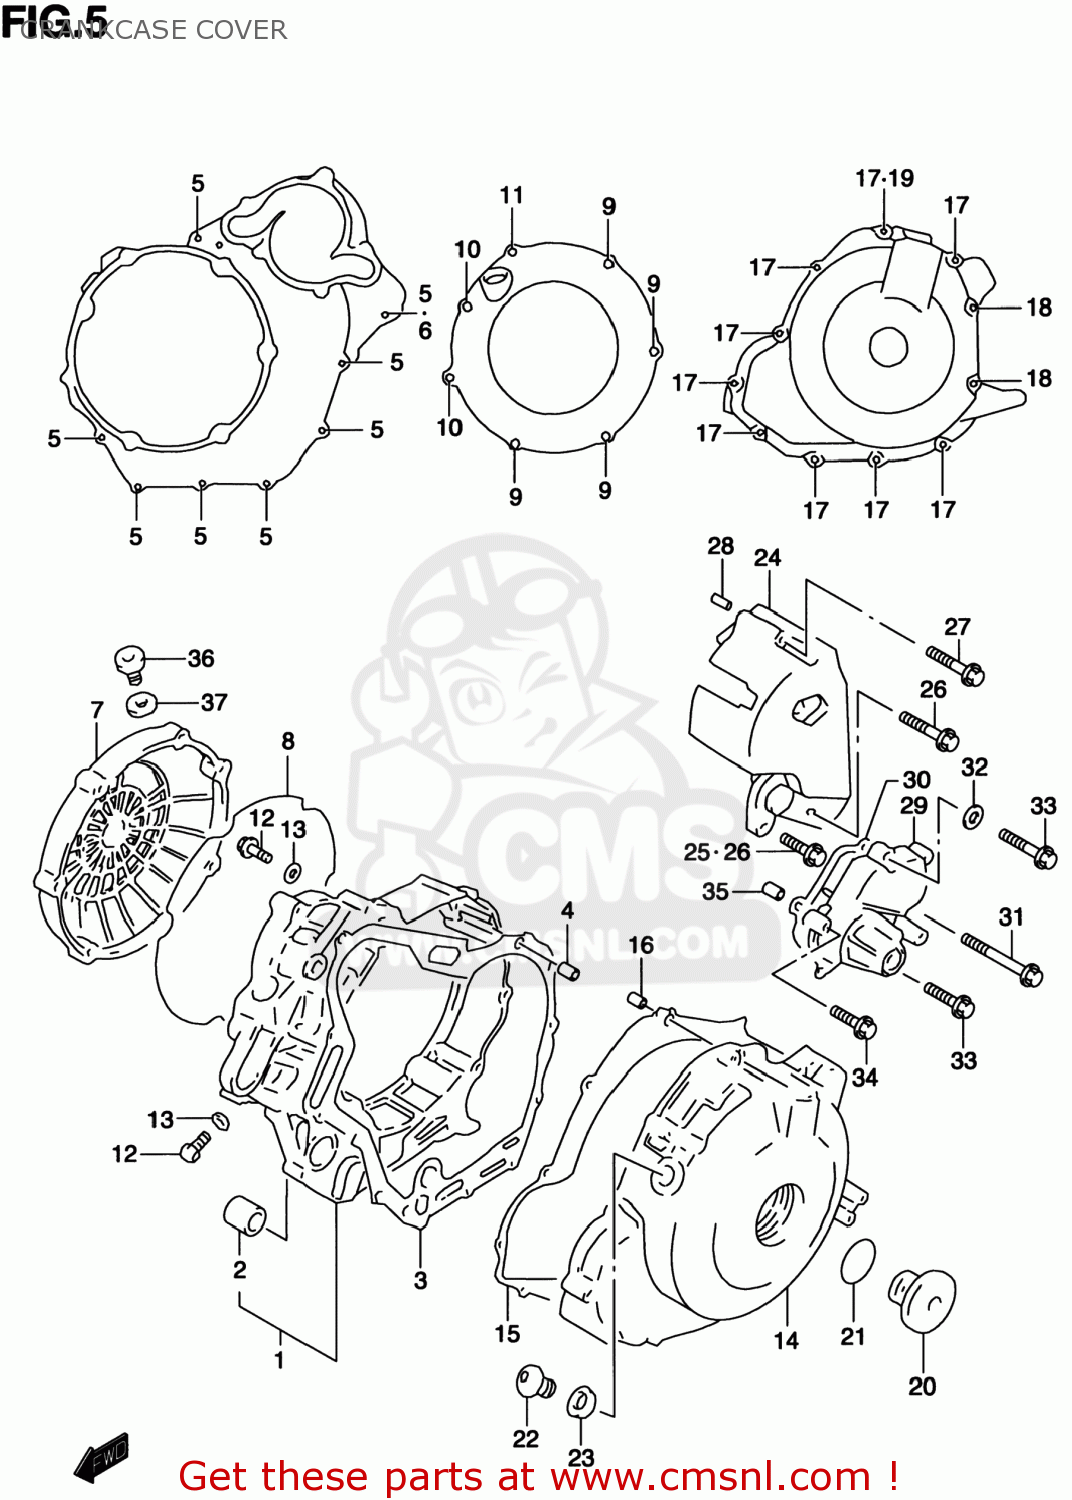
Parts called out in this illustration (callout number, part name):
1	COVER,CLUTCH
2	LENS,OIL LEVEL CHECK
3	GASKET,CLUTCH COVER (NAS)
4	PIN
5	BOLT,G/S SWITC
6	GASKET(5.8X11X1.2) (NAS)
7	COVER,CLUTCH OUTER
8	O RING,CLUTCH COVER OUTER
9	BOLT
10	BOLT
11	BOLT
12	BOLT
13	GASKET(6.2X11X1).2 (NAS)
14	COVER,MAGNETO
15	GASKET,MAGNETO COVER (NAS)
16	PIN
17	BOLT
18	BOLT
19	GASKET(5.8X11X1.2) (NAS)
20	PLUG
21	O RING(D:3.1,ID:32.7)
22	PLUG,14X12
23	GASKET(13.8X18.8X4.8) (NAS)
24	COVER,ENGINE SPROCKET
25	BOLT
26	BOLT
27	BOLT
28	PIN
29	COVER,GEAR SHIFT
30	GASKET,GEAR SHIFT COVER (NAS)
31	BOLT(6X105)
32	GASKET(5.8X11X1.2) (NAS)
33	BOLT
34	BOLT
35	PIN
36	PLUG
37	O RING(D:3.1,ID:16.8)
